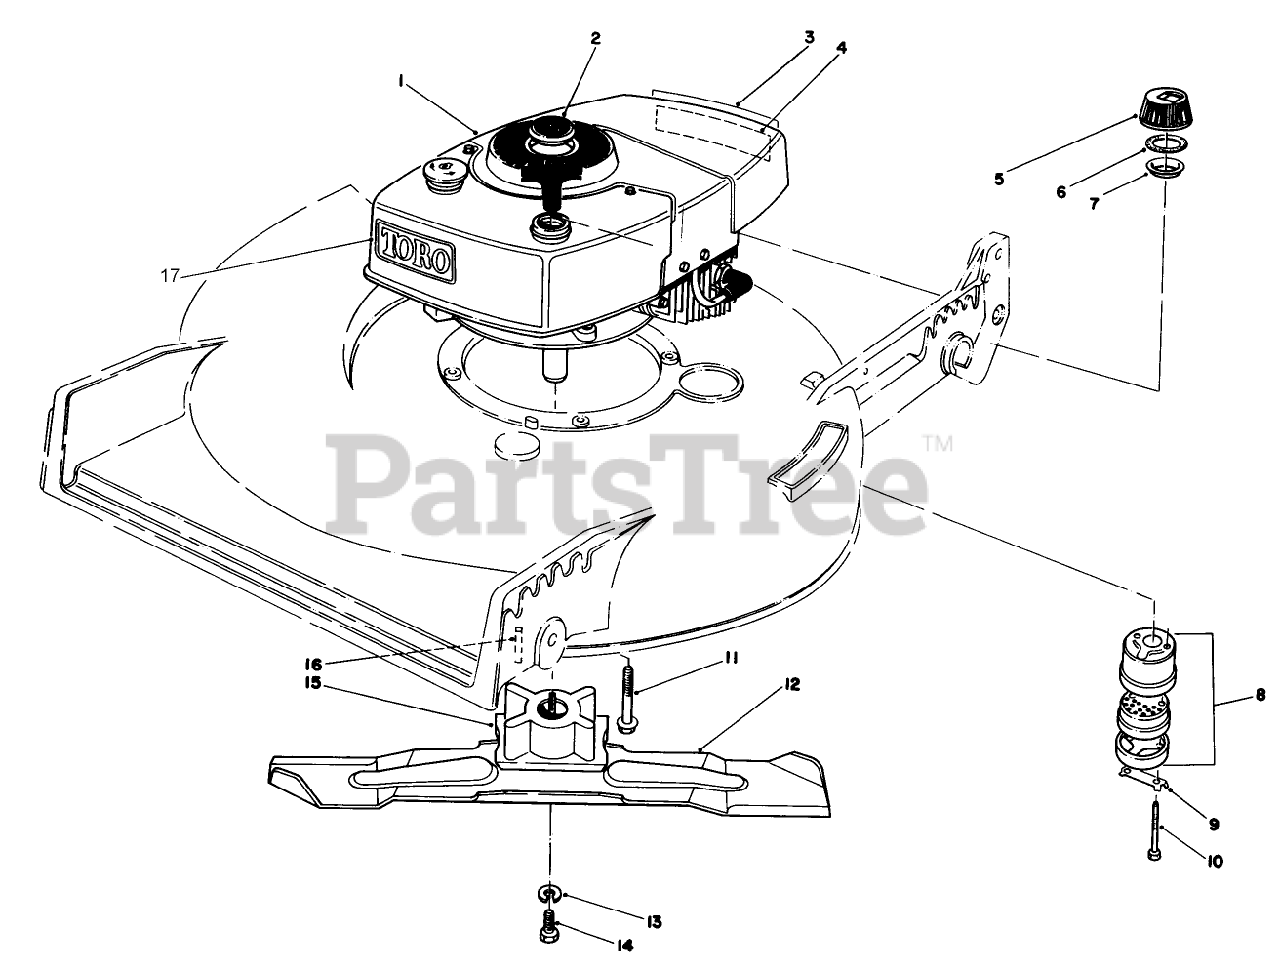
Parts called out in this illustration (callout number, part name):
1	Engine
2	Plug Button
3	Decal-Primer
4	Decal Maintenance
5	Gas Cap Assembly (Incl. Ref. #6 & 7)
6	GASKET
7	Baffle-Gas Cap
8	Muffler Assembly (Incl Ref. #9 & 10)
9	CLIP - LOCKING
10	SCREW-HH
11	3/8-16 X 2 CAPSCREW
12	BLADE-21in
13	WASHER-LOCK
14	SCREW-BLADE
15	BLADE RETAINER(DEEP)
16	KEY-SQUARE
17	Decal Tow
